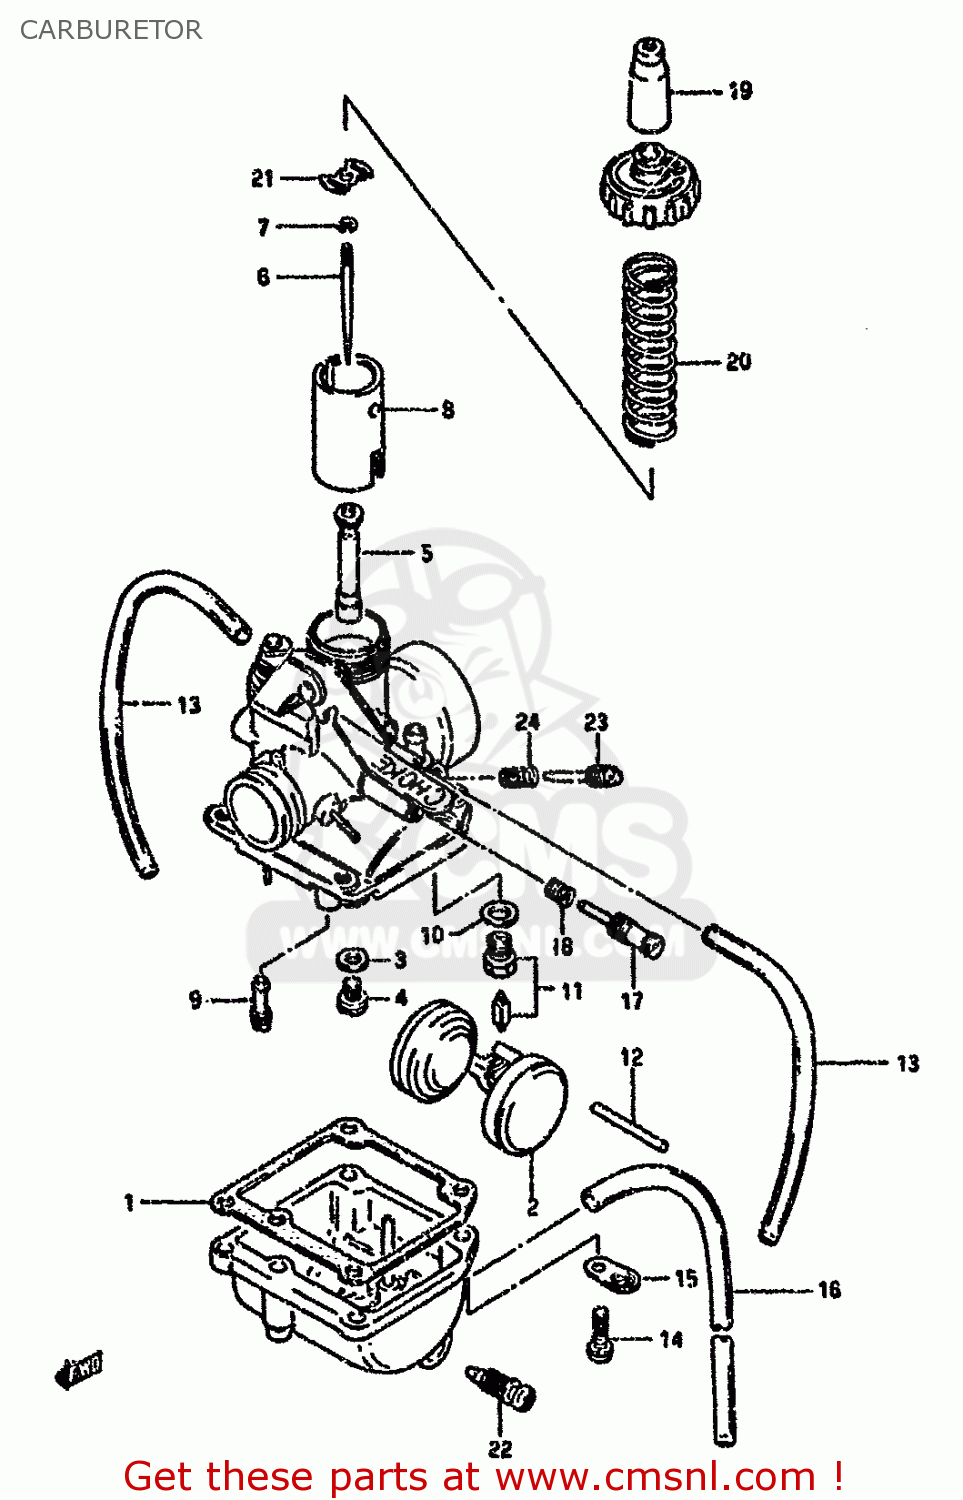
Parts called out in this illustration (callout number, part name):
1	GASKET,FLOAT CHAMBER (NAS)
2	FLOAT
3	WASHER,NEEDLE NOZZLE
4	JET,MAIN(85)
5	JET,NEEDLE(P-1)
6	NEEDLE,JET(4DN3-2)
7	CLIP
8	VALVE,THROTTLE(CA:1.5)
9	JET,PILOT 20
10	GASKET,NEEDLE VALVE (NAS)
11	VALVE ASSY,NEEDLE
12	PIN,FLOAT
13	HOSE(3X5X650)
14	SCREW
15	PLATE
16	HOSE
17	SCREW,THROTTLE STOP
18	SPRING,THROTTLE SCREW
19	CAP,CABLE ADJUSTER
20	SPRING,THROTTLE VALVE
21	STOPPER,NEEDLE CLIP
22	PLUG,DRAIN
23	SCREW,PILOT AIR
24	SPRING
